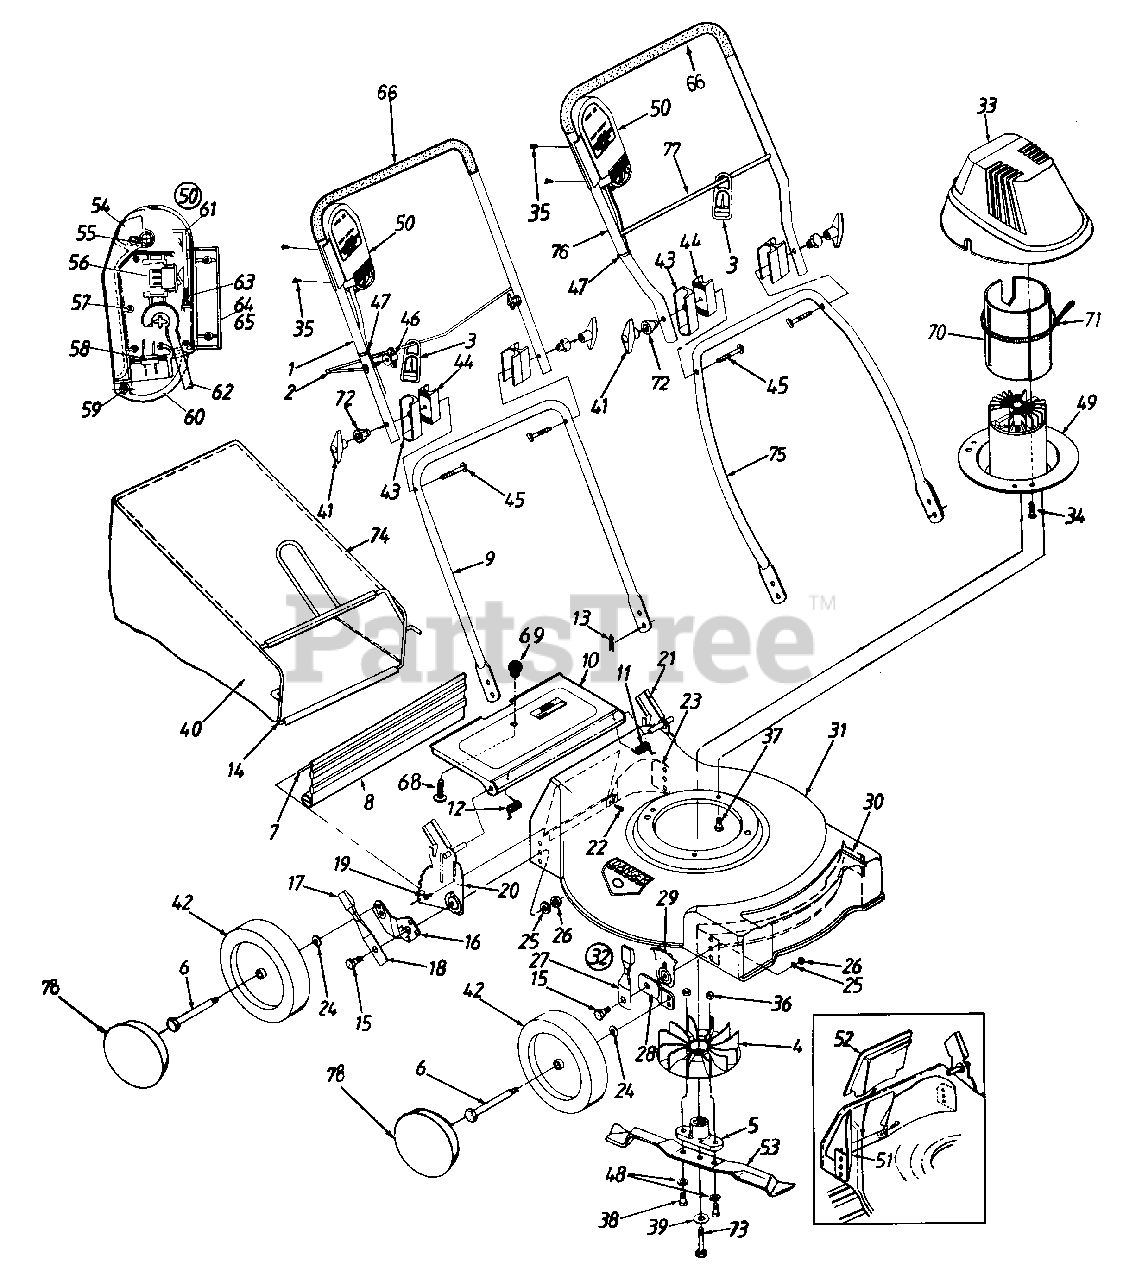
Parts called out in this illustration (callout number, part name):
3	Strain Relief-Cord
5	Blade Adapter
6	Axle Bolt
7	Rear Flap Wire
8	Rear Flap
12	Door Spring-R.H.
13	Hairpin Clip
16	Pivot Bar-R.H.
17	Spring Lever Knob
18	Spring Lever
19	Hex L-Wash. Hd. AB-Tap Scr. 1/4 x .62" Lg.
20	Handle Brkt. Ass'y.-R.H.
21	Handle Brkt. Ass'y.-L.H.
22	Torx . Mach. AB-Tap Scr. 1/4 x .62" Lg.
25	Bell-Wash. .39" I.D. x 1.38" O.D.
26	Hex Nut 3/8-16 Thd.
27	Spring Lever Ass'y. w/Knob
29	Height Adj. Plate
33	Motor Cover
34	Scr. #10-16 x .75" Lg.
35	Self-Tap. Scr. #7 x 1" Lg.
36	Hex Nut 3/8-24 Thd.
37	Hex L-Wash. TT-Tap Scr. 3/8-16 x .75" Lg.
38	Hex Bolt 3/8-24 x 1.25" Lg.
39	Bell-Wash. .396" I.D. x 1.14"
40	Grass Bag
41	Plastic Knob
42	Wheel Ass'y. Comp. (8" x 1.75")
43	Upper Handle Insulator
44	Lower Handle Insulator
45	Carriage Bolt 5/16-18 x 3" Lg.
46	Wing Nut 1/4-20 Thd.
47	Cable Tie
48	Bell-Wash. 3/8" I.D.
49	Motor, Cord & Switch Ass'y.
50	Cord & Switch Ass'y. Comp.
53	19" Mulching Blade
54	Handle-Switch Actuator
55	Spring-Switch Handle
56	Switch
57	Screw #6-32 x .5" Lg.
58	Plug Ass'y.
59	Retainer Plug Spring
60	Retainer Plug
61	Latch
62	Cord Ass'y.
63	Spring Latch
64	Housing-Upper Half
66	Foam Grip
68	Truss Scr. #10-24 x .38" Lg.
70	Insulator
71	Cable Tie
72	Insulator Knob
73	Hex Bolt 3/8-24 x 2.5" Lg.
77	Cord Control Rod
78	Hub Cap
